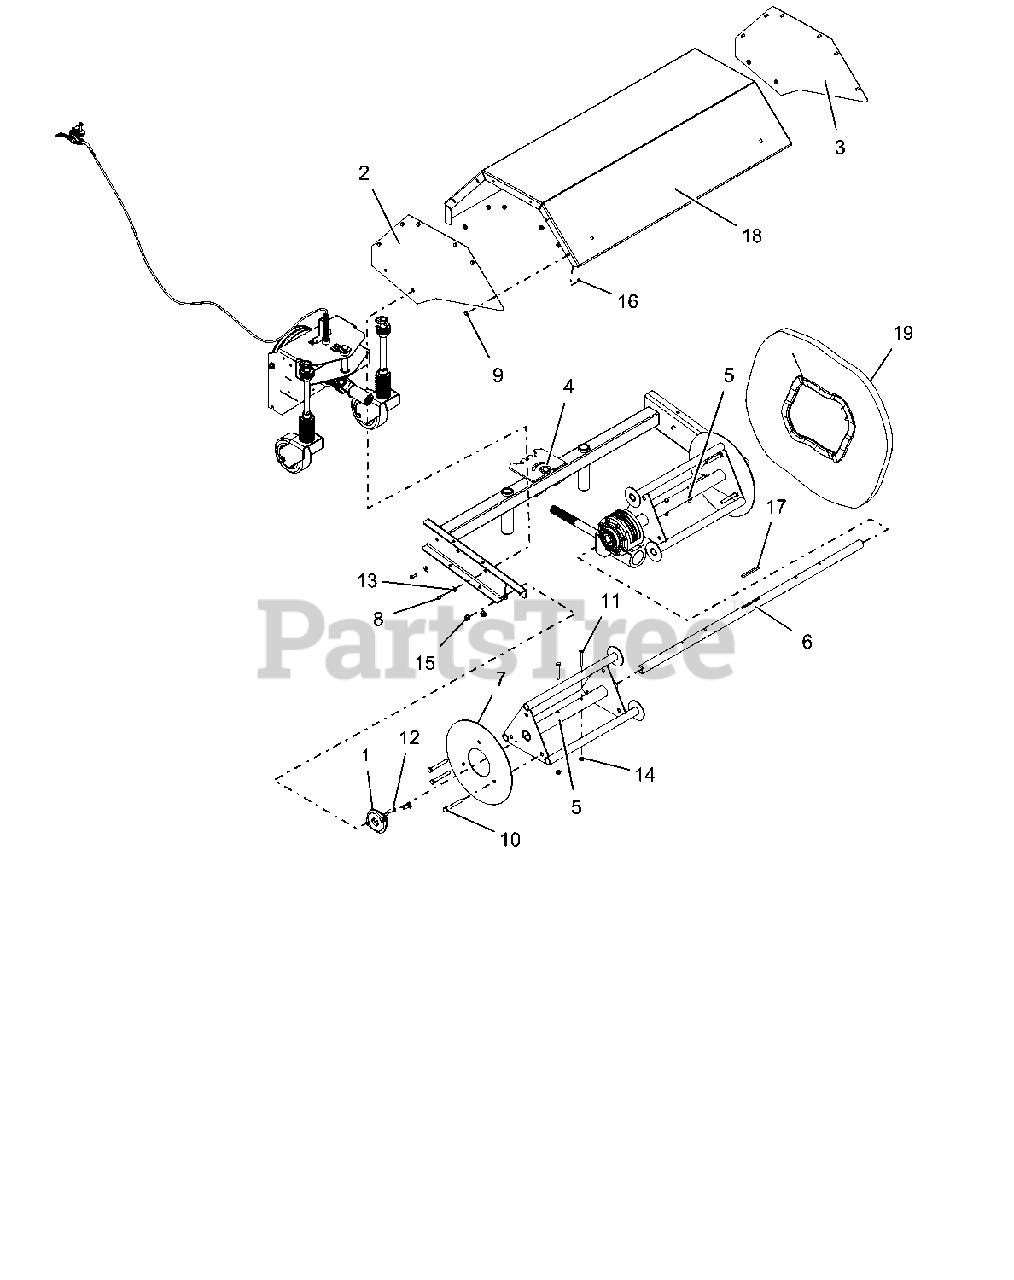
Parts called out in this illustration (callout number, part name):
1	BEARING,2 BOLT FLANGE 1-1/8 ID
2	WLDT, SIDE COVER - RH
3	WLDT, SIDE COVER - LH
4	FRAME, POWER BROOM 36"
5	PB36 DRIVE CORE SERVICE KIT
6	CENTER, SHAFT
7	PLATE, END RETAINER
8	BLT-HEX .25-20X.75 GR5 YWZC
9	BLT-HEX .25-20X.50 GR5 YWZC
10	BLT-HEX .38-16X3.00 GR5 FTH YZ
11	BLT-HEX .31-18X2.25 GR5 YWZC
12	BLT-RDHDSQNK .38-16X1.00 G5YZ
13	WSHR-FL-STL.312X.734X.065 YWZ
14	NUT-LK-CTR .31-18 YWZC
15	NUT-LK-TOP-FLG .38-16 YWZC
16	NUT-LK-TOP-FLG .25-20 YWZC
17	KEY .25 X .25 X 3IN
18	COVER,TOP-36" BRUSH W/DECALS
19	KIT, BRISTLE - SET OF 18
